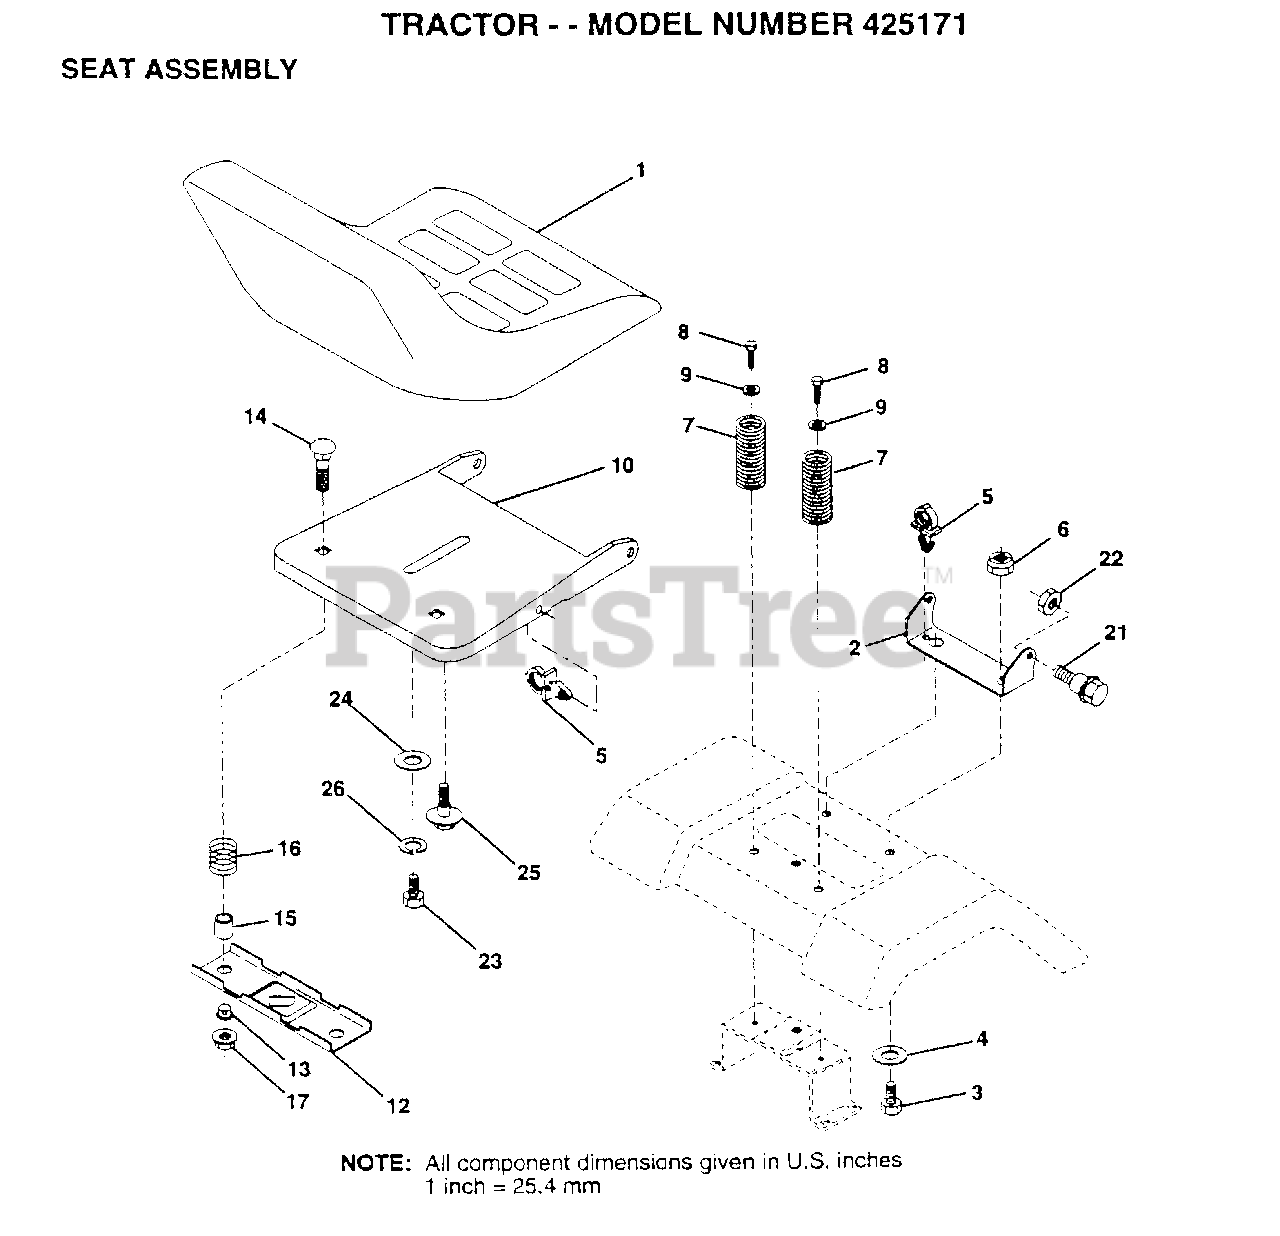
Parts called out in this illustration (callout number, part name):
2	BRACKET PVT SEAT
3	BOLT
4	WASHER PM
5	CLIP.PUSH-IN.HING
6	NUT
7	SPRING COMPRESSIO
8	SCREW GTV
9	WASHER
12	BRKT SWITCH
13	BUSHING
15	SPLIT SPACER
16	SPRING
21	BOLT.SHLD.5/16-18
22	NUT
23	BOLT
24	WASHER
25	"BOLT,SHOULDER"
26	LOCKWASHER
